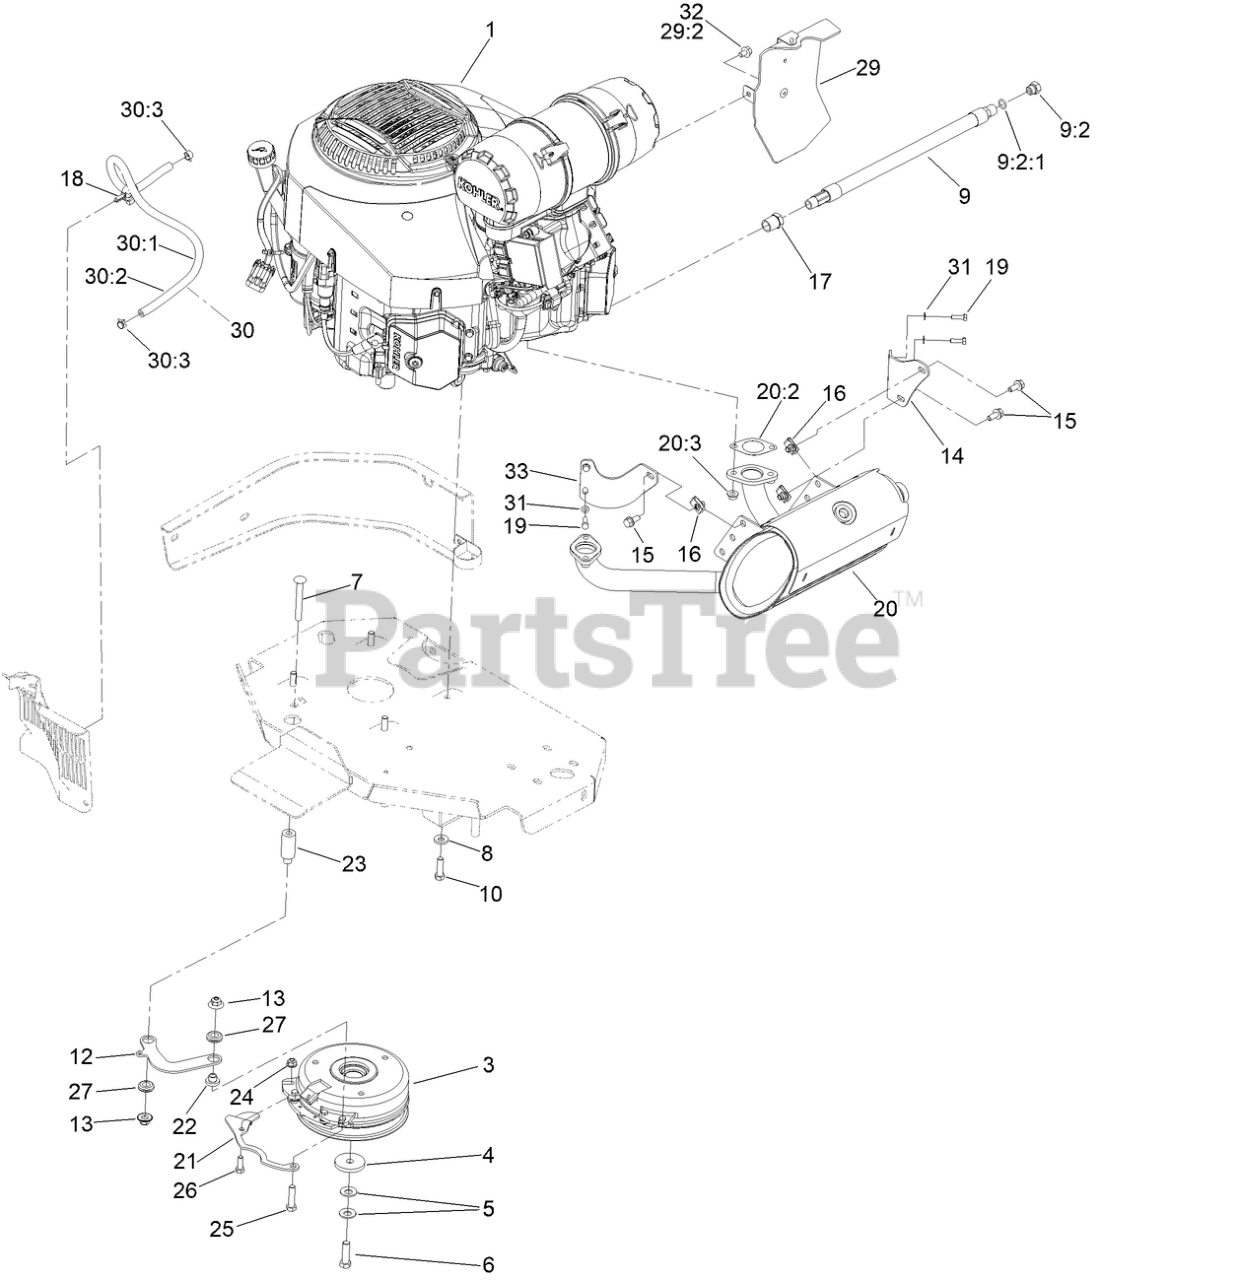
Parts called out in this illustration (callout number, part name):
3	WASHER-CLUTCH
4	WASHER-SPRING
5	SCREW-HH 7/16-20 X 1 1/2 W/LOCTITE
6	SCREW-CARR
7	WASHER-BELLEVILLE
8	OIL DRAIN HOSE ASM
9	PLUG-HH
9:2	O-RING
9:2:1	SCREW-HH
10	LINK-ANCHOR, CLUTCH
12	Nut-Nyloc 3/8-16 Flg
13	BRACKET-MUFFLER
14	SCREW-HHF
16	BUSHING
17	CLAMP-HOSE
18	SCREW-HH M6-1 X 20Mm W/Patch
19	MUFFLER-940-980 KOH EFI
20	MUFFLER-940-980 KOH EFI
20	MUFFLER KIT
20:2	GASKET-EXHAUST
20:3	NUT-FLANGE, LOCK
21	BELT-GUIDE
24	NUT-HF, NI
25	SCREW-HH
26	SCREW-HH
27	GROMMET-RUBBER
29	Baffle Kit
29:2	SCREW-HWH
29:2	Screw-HHF
30	FUEL LINE ASM
30:1	HOSE-FUEL
30:2	SLEEVE, THERMAL
30:3	CLAMP-HOSE
31	WASHER-SPRING
32	Screw-HHF
33	BRACKET-MUFFLER, FRONT
